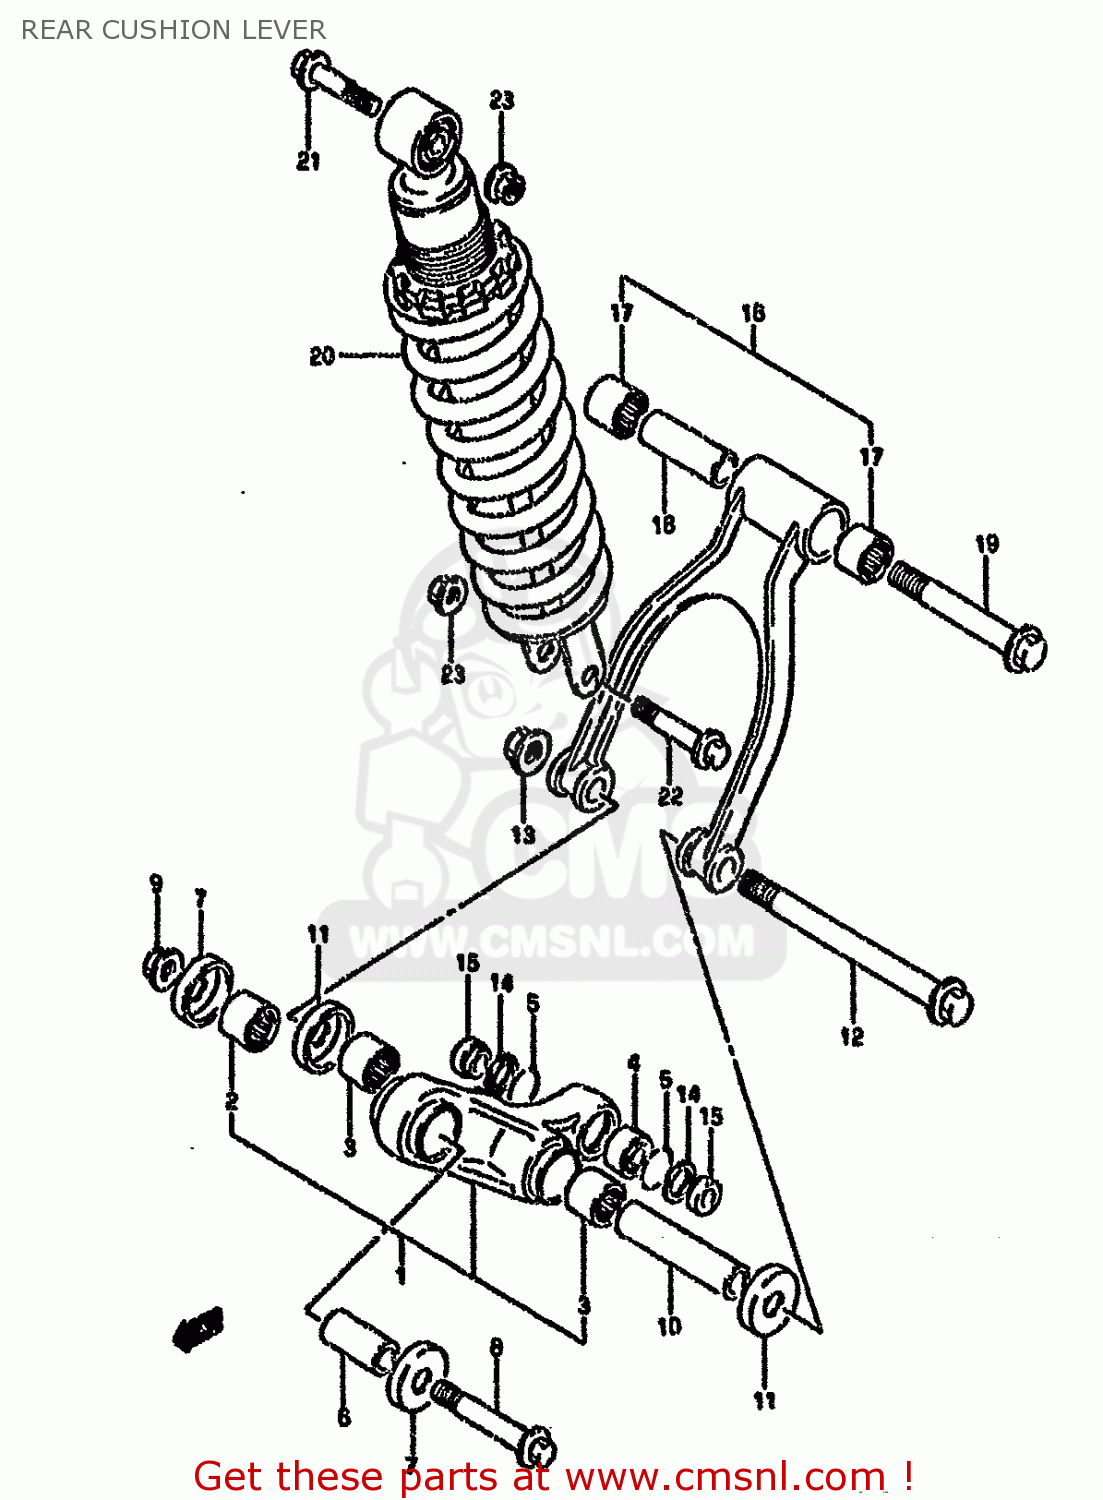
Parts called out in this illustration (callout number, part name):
1	LEVER SET,REAR CUSHION
2	BEARING(20X27X30)
3	BEARING(20X27X23.5)
4	BEARING,RR CUSHION LEVER
5	RING,STOPPER
6	SPACER,RR CUSHION LEVER FR
7	SEAL,RR CUSHION LEVER FR DUST
8	BOLT,RR CUSHION LEVER FR
9	NUT 12MM
10	SPACER (14X20X78)
11	SEAL,RR CUSHION LEVER CTR DUST
12	BOLT,RR CUSHION ROD LWR
13	NUT
14	SEAL,DUST RR SHOCK ABSORBER
15	COLLAR
16	ROD SET,REAR CUSHION,LEFT
17	BEARING(20X27X23.5)
18	SPACER (14X20X63)
19	BOLT,RR CUSHION ROD UPR
20	ABSORBER ASSY,REAR SHOCK (BLUE)
21	BOLT(10X50)
22	BOLT(10X52)
23	NUT
